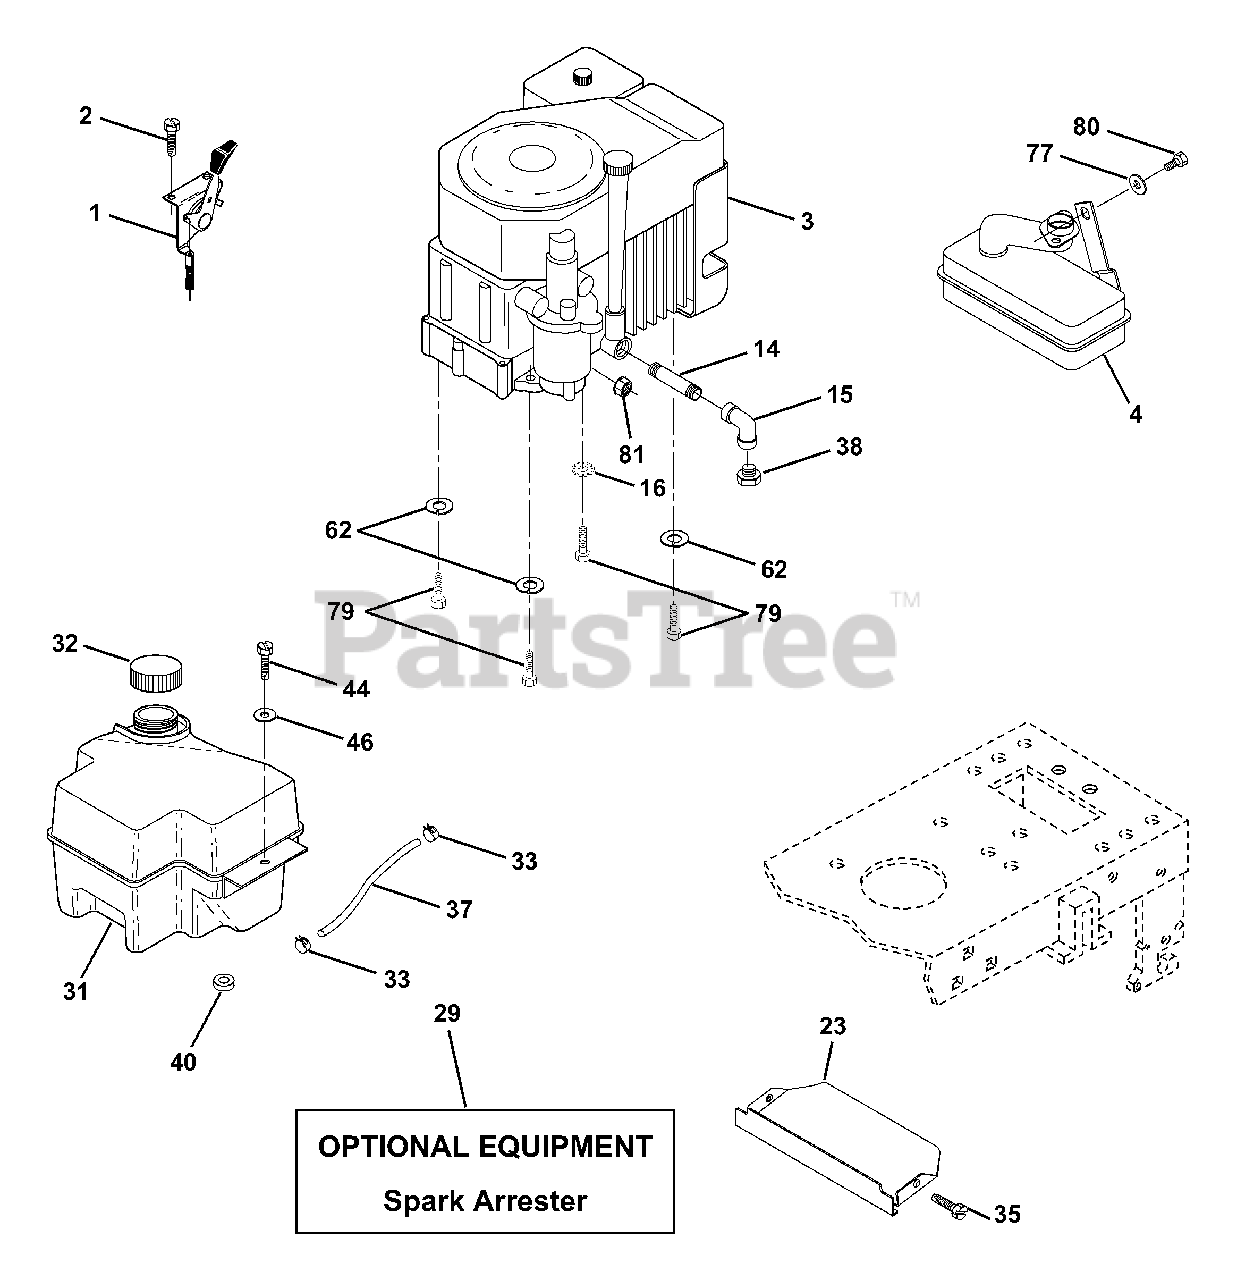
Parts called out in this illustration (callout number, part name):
1	Control THTICH 27 LH FLAG DOM
2	Screw Hex Thd Cut 1/4-20 x 5/8 T
4	Muffler LT Kohler 12.5/15HD
14	Nipple Pipe 3/8 Npt X 3-1/2
15	Elbow Std 90 Degree 3/8-18 Npt
16	Washer Lock Ext Tooth 5/16
23	Shield Browning/Debris Guard
29	Kit Spark Arrestor (Flat Scrn)
31	Tank Fuel Front 2 00 Gal Nat
32	Cap Asm Fuel W/sym Vented
33	Clamp Hose Black
35	Screw
37	Line Fuel 20"
38	Plug Oil Drain
40	Bushing Snap Nyl Blk Fuel Line
44	Screw Hexwsh Thdrol 1/4-20x3/4
46	Washer 9/32 X 7/8 X 16 Ga
62	Washer Lock Hvy Hlcl Spr 5/16
77	Washer 5/16 x 3/4 x 16 Ga.
79	Bolt Hex
80	Bolt Hex Hd 5/16-18 UNC x 1/2
81	Nut Flange 1/4-20 Starter Nut
